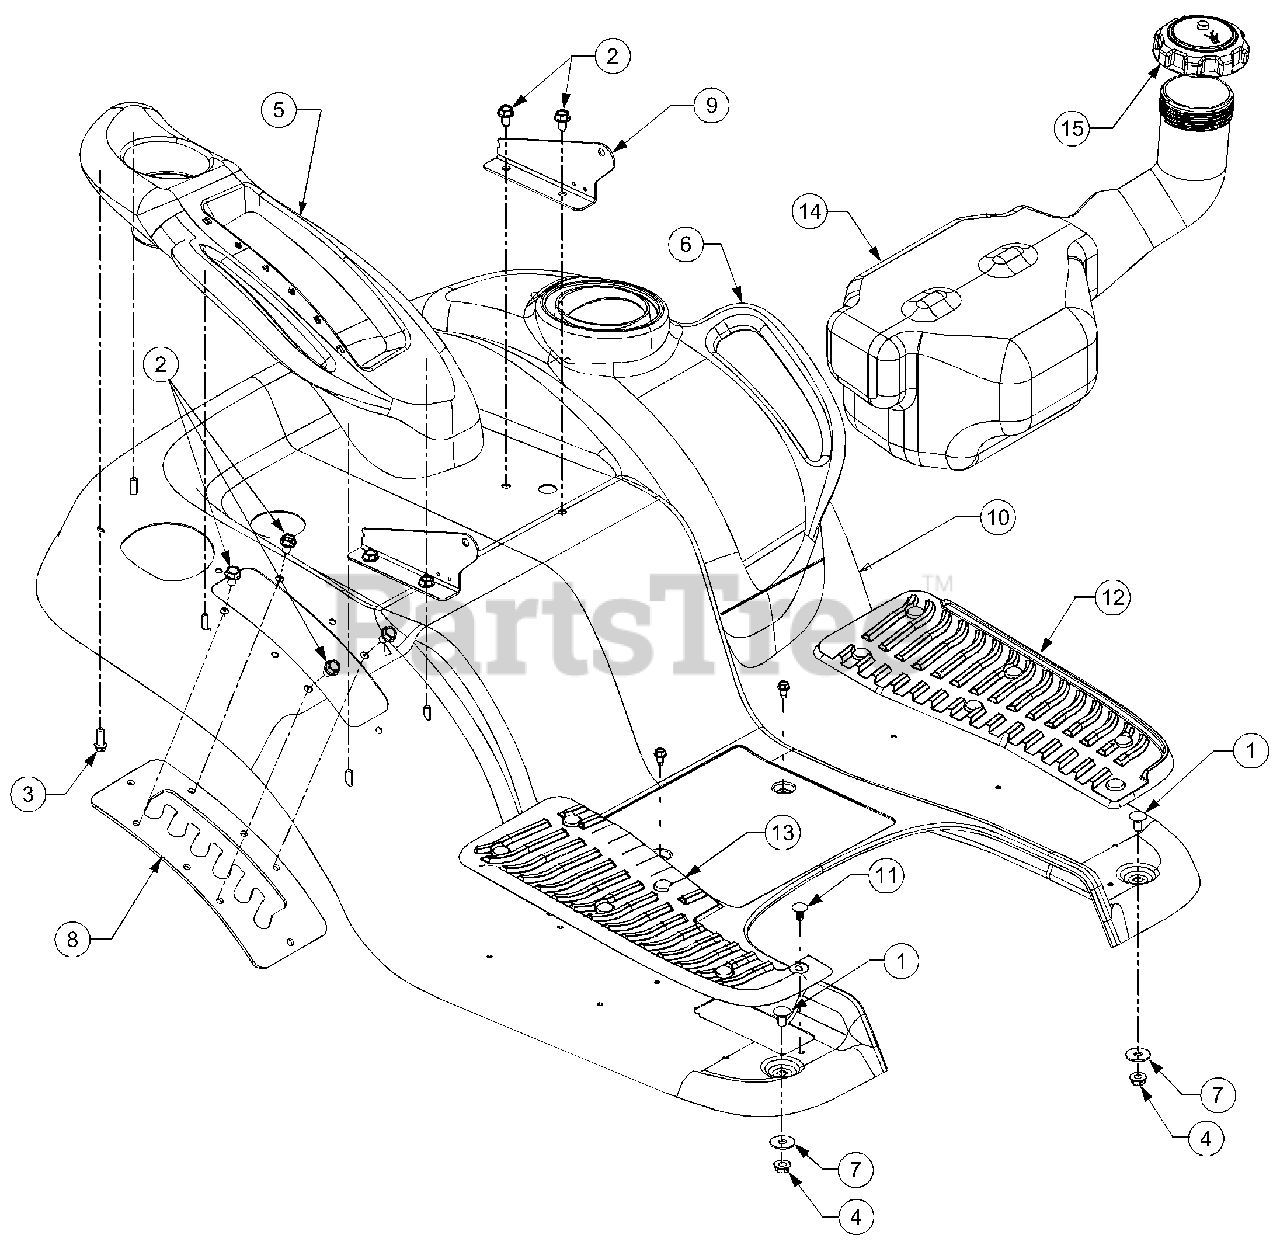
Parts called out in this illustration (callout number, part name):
1	Bolt, Carriage, 5/16-18 x .62 Lg
2	Screw, 5/16-12, 0.75
3	Screw, 1/4-15, 0.750
4	Nut, Nylon Lock, 5/16-18
5	Cover, Fender, RH
6	Cover, Fender, LH
7	Washer, Flat, .349 x 1.00 x .063
12	Pad, Foot, LH
13	Pad, Foot, RH
14	Tank, Fuel
15	Cap, Fuel
16	Screw, Self-tapping, 1/4-20, 0.500
